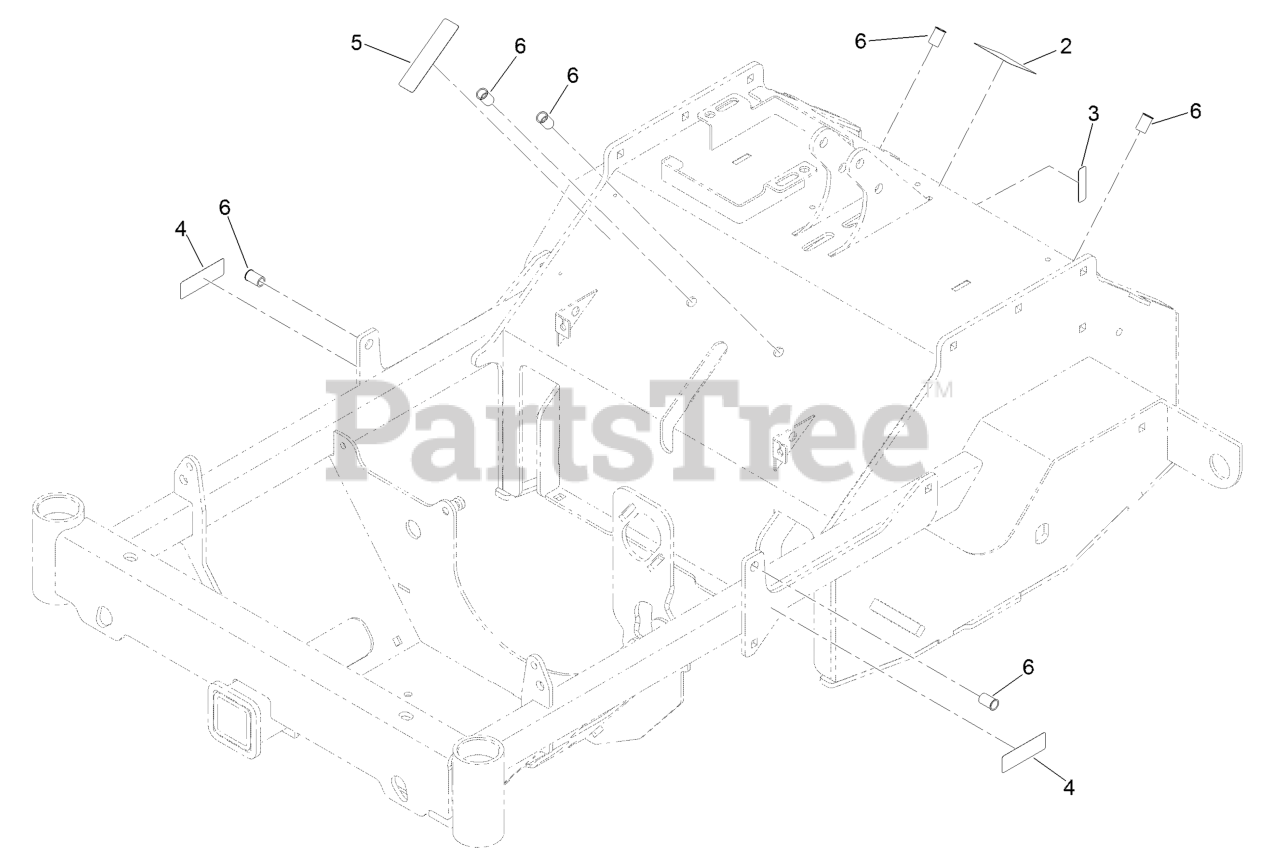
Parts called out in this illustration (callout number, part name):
2	Decal-Warning
3	Decal-Warning
4	Decal-Danger
5	Decal-Arrester, Spark
6	Insert-Nut
